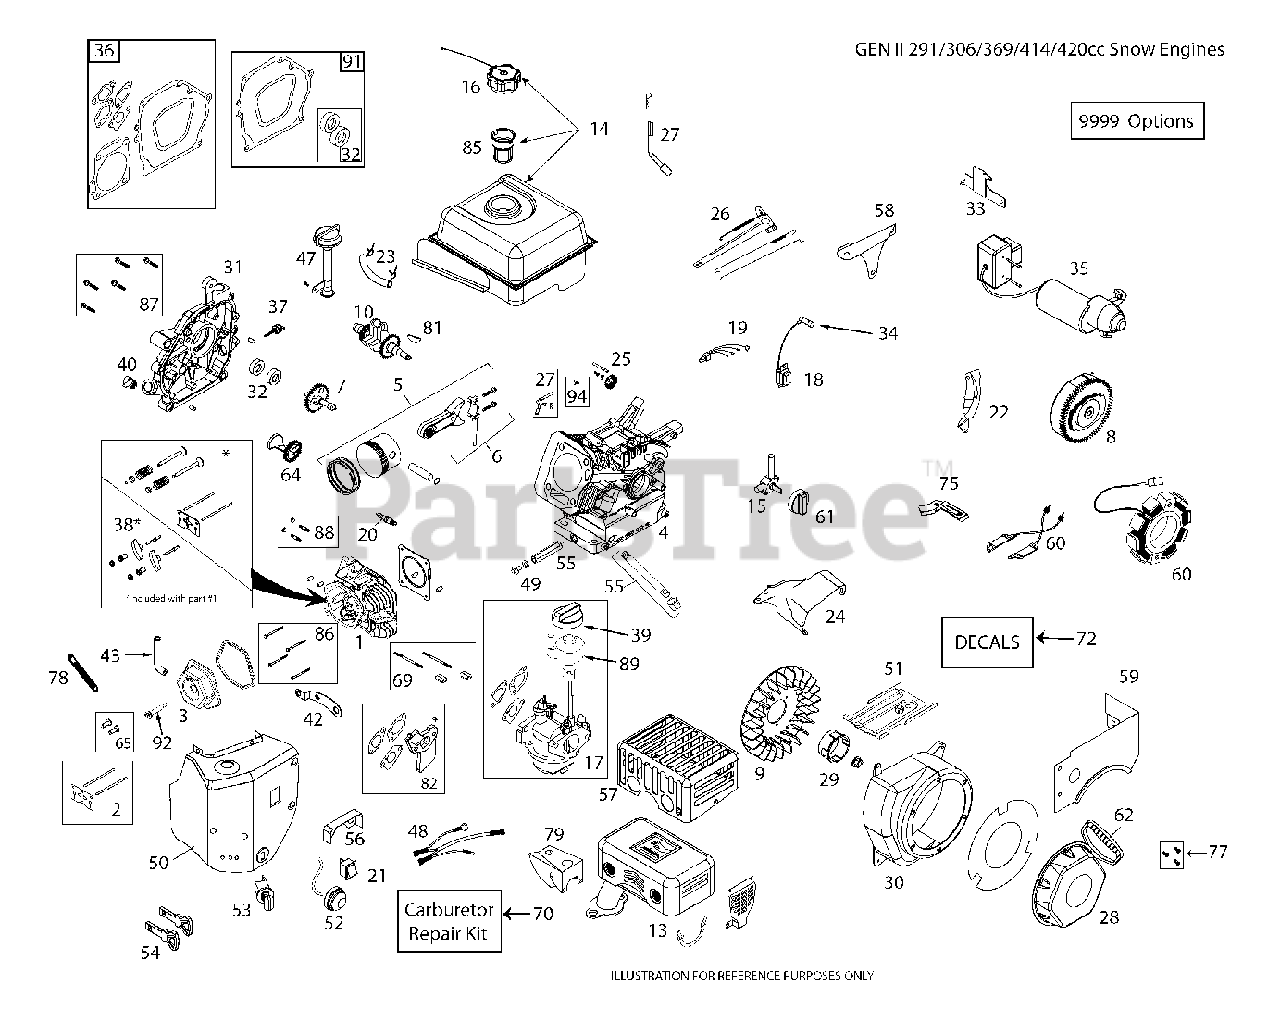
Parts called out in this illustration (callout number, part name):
1	CYLINDER.HEAD.ASSY(SK2911000)
2	PUSH ROD TAPPET KIT
3	VALVE.COVER(SK4144500)
5	PISTON.AND.ROD.ASSY(SK2911400)
6	CONNECTING ROD ASSY SNO.LCT
7	CAMSHAFT(SK2911600)
8	FLYWHEEL.EL.ST.SKSNO2401.1
9	FLYWHEEL.FAN
10	CRANKSHAFT LCT.SKSN2805.1
13	MUFFLER (SKSN2210.1)
14	FUEL TANK ASSY - SNOW (291CC)
15	FUEL.PETCOCK.SNOW(SKSN4900)
16	FUEL.TANK.CAP.SNOW(SKSN4301)
17	Carburetor, LCT
18	COIL.IGN.CDI.SKSN2403.1
20	SPARK.PLUG(SK2911550)
21	ON/OFF.SWITCH.SNOW(SKSN4403)
22	SHIELD.U/FYWHL.CHARG(SKSN4604)
23	FUEL HOSE KIT
24	TOP.SHIELD.LCT.
25	GOVERNOR.GEAR.ASSY(SK2912900)
26	GOVERNOR.ARM.ASSY.(SKSN2502)
27	GOVERNOR.SHAFT.(SK2913100)
28	RECOIL.START.ASSY.(SKSN2600)
29	STARTER.CUP.SMALLSNOW(SKSN2601
31	CRANKCASE.COVER.ASY(SK2913600)
32	OIL.SEAL.KIT(SK2913900)
33	SWITCHBOX BRACKET ES LCT 291 S
34	SPARK.PLUG.BOOT.SNW,SKSN4691.1
35	ELECTRIC.START.ASSY(SKSN2400)
36	ENGINE.GASKET.KIT(SK2914300)
37	DIPSTK.OIL.BLK.LCTSK4143711.1
38	ROCKER ARM KIT
39	CHOKE.KNOW.SNOW(SKSN4500)
40	NONREMVABLE.OIL.PLUG(SK4143715
42	CDI.BOX.BRKT.SNOW(SKSN4402)
43	Breather Tube, LCT 291/369/414
47	High Oil Fill Assembly Kit
48	WIRE.HARNESS(SKSN4406)
49	OIL.DRAIN.PLUG
50	HEATER.BOX.ASSY.SNOW(SKSN2100)
51	SHIELD.CYLINDER.SNOW(SK4141010
52	PRIMER.BULB.ASSY(SKSN4304)
53	KEY.SWITCH.ASSY.SNOW(SKSN4401)
54	KEY SET(2 KEYS) SKSN0407.1
55	OIL PIPE DRAIN EXTENDED.LCT SK
56	SHIELD.VAPOR(SKSN4606)
57	SHIELD.MUFFLER.
58	GOVERNOR.LINK.SHIELD(SKSN2501)
59	FUEL.TANK.SKIRT(SKSN2101)
60	ALTERN.60WATT.SKSN2402.1
61	FUEL KNOB-SNOW
62	HANDLE.RECOIL.DEL.SKSN0613.1
65	TAPPET KIT.LCT.SK2911005.1
69	STUD.CARB.MOUTING.KIT.291CC
70	Carburetor Repair Kit, 291CC/4
77	Recoil Bolt Kit, LCT
81	Flywheel Keys, 136/291cc 5-Pack
82	Carburetor Spacer, 291CC LCT
85	Fuel Tank Strainer, LCT 208cc
86	KIT.BOLT.CYLINDER.HEAD.(4PC)
87	Crankcase Cover Bolt Kit, 291cc
88	STUD.MUFFLER.KIT.LCT
89	Speed Knob, LCT Sksn5325.1
91	GASKET KIT CRANKSHAFT.LCT
92	CENTER VALVE COVER BOLT
9999	HIGH.ALTITUDE.JET.(>6,000FT)
